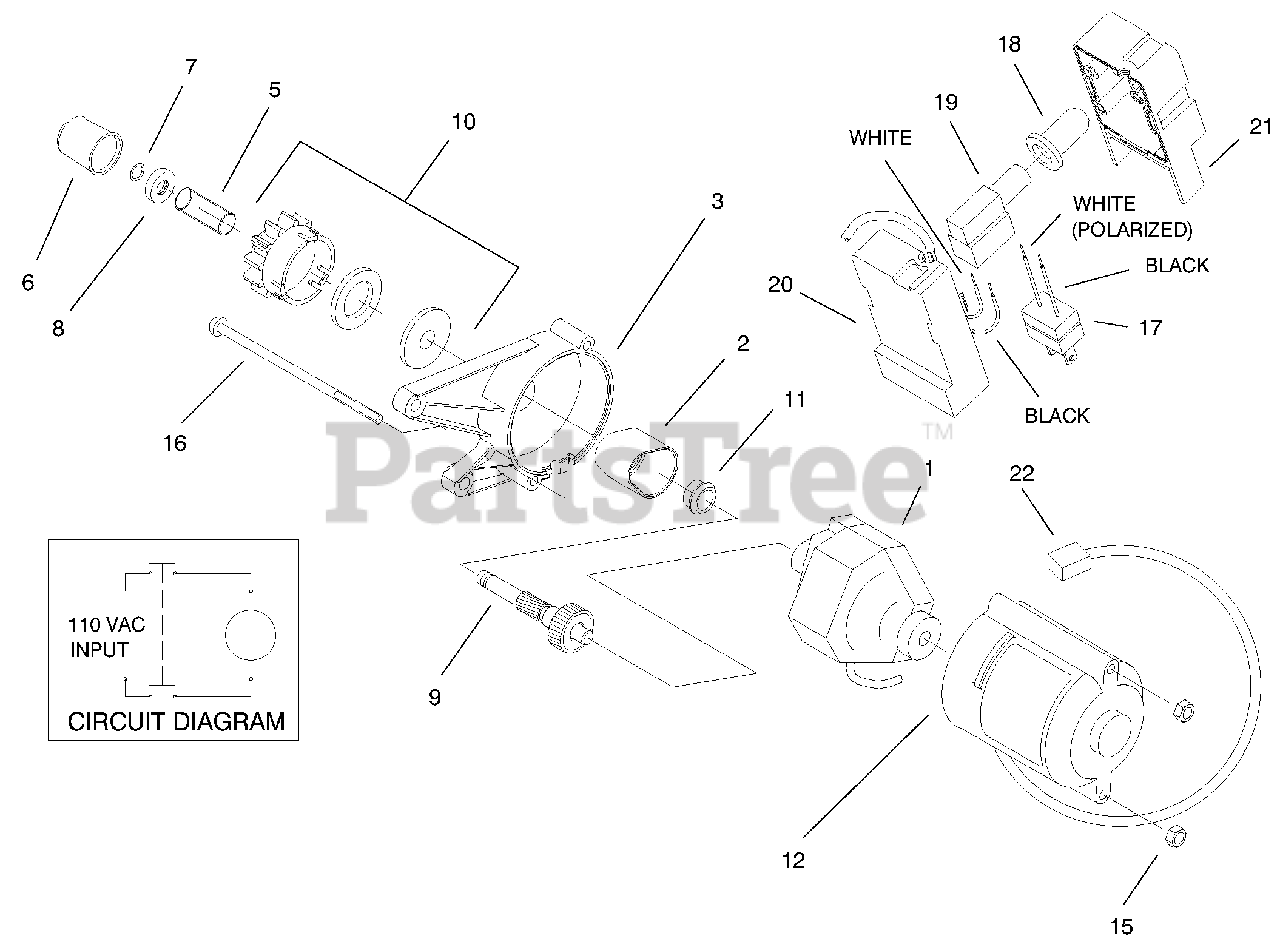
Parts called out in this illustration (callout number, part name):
1	ASM-Motor
2	Cover-Gear
3	Housing-Starter
5	Spring-Anti Drift
6	Cap-Pinion
7	Ring-Lock
8	Stop-Pinion
9	ASM-Shaft & Gear
11	Bushing-Upper
12	Housing-Lower
15	Nut-Lock
16	Screw-PPH
17	Plug-Power
18	Boot-Switch
20	Base-Switch Hsg
21	Cap-Switch Hsg
22	Tie-Cable
